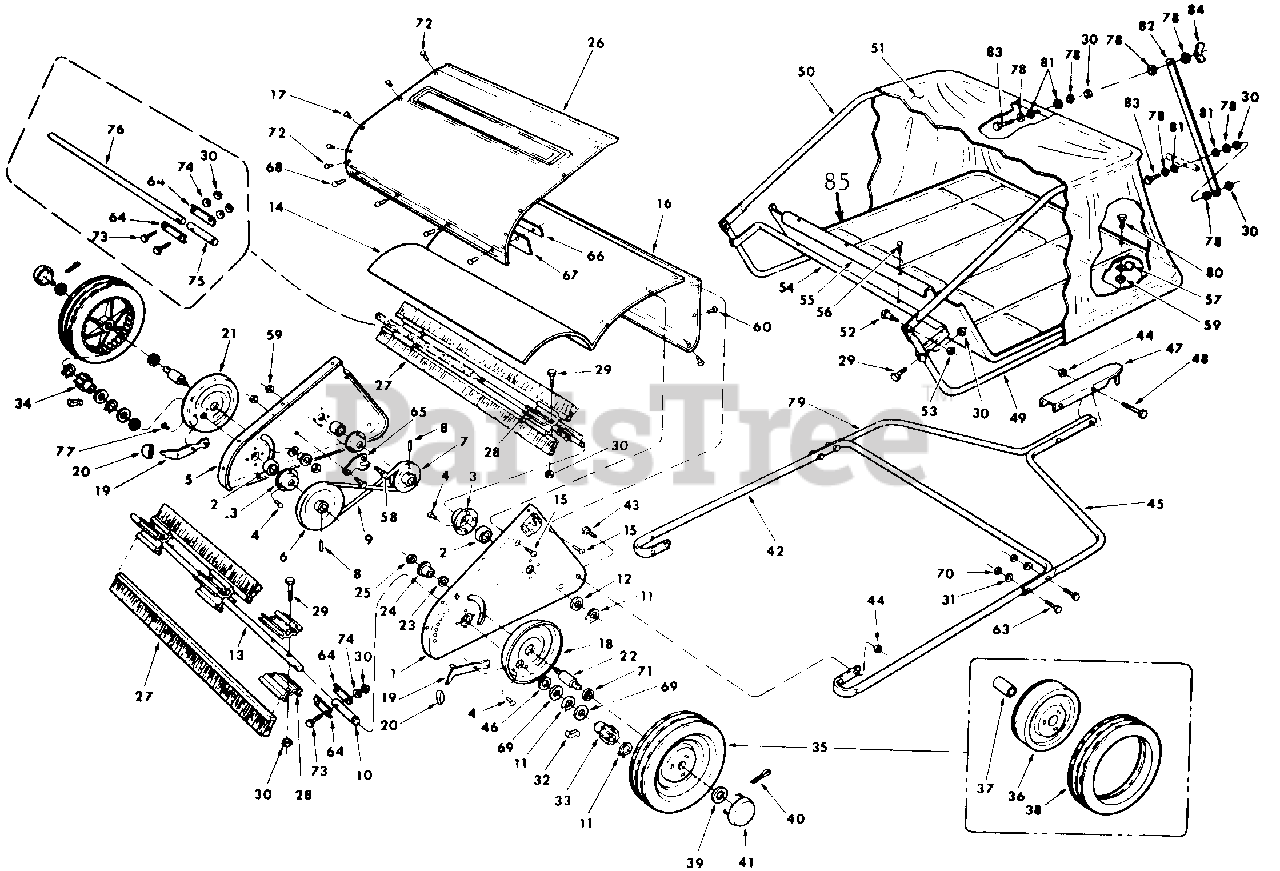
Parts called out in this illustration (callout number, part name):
1	Assembly-End Plate R.H.
2	Bearing
3	Retainer-Bearing
4	Rivet (3/16 Dia. x 5/16)
5	Assembly-End Plate L.H.
6	Assembly-Pulley
7	Pulley
8	Rollpin (.156 Dia. x 1-1/4)
9	Belt (3/8 Round Sect.)
10	Shaft-Brush Drive
11	Ring-Retainer
12	Washer-Flat (5/8 x 15/16 x 1/16)
13	Shaft-Brush Drive
14	Baffle-Top
15	Screw (10-32 x 1-1/8 Sems) *
16	Baffle-Front
17	Screw (10-32 x 3/8 Sems) *
18	Assembly-Dust Cover R.H.
19	Assembly-Wheel Adj. Lever
20	Knob-Wheel Adj.
21	Assembly-Dust Cover L.H.
22	Axle-Wheel
23	Washer-Bowed
24	Bushing-Spacer
25	Nut-Hex
26	Cover-Sweeper
27	Ass'y. Brush and Channel
28	Assemblv-Brush Retainer
29	Bolt (1/4-20 x 1-1/8 Hex Hd.) *
30	Nut (1/4-20 Hex Lock) *
31	Washer-Lock (5/16 Split)
32	Pawl
33	Pinion R.H.
34	Pinion L.H.
35	Assembly-Wheel
36	Wheel-Gear & Rim
37	Bushing
39	Washer (3/8 x 7/8 x 3/16) *
40	Cotter Pin (1/8 x 5/8) *
41	Cap-Hub
42	Draw-Bar-Rear
43	Bolt (5/16-18 x 3/4 Sem Hex) *
44	Nut (5/16-18 Hex Lock) *
45	Draw-Bar-Front
46	Washer-Bowed
47	Ass'y.-Bracket & Pin
48	Bolt (5/16-18 x 2-5/8 Hex Hd.) *
49	Frame Catcher-Lower
50	Frame Catcher-Upper
51	Basket-Fabric
52	Bolt-Shoulder
53	Nut (3/8-16 Hex Lock) *
54	Brace-Frame
55	Panel-Catcher Bottom
56	Screw (10-32 x 1/2 Phillips) *
57	Clamp
58	Bolt (10-32 x 3/8 Truss Hd.) *
59	Nut (10-32 Hex Lock) *
60	Screw (10-32 x 3/8 Sems) *
63	Bolt (5/16 x 1-3/8)
64	Coupling-Half
65	Scraper-Impeller Pulley
66	Retainer-Skirt
67	Skirt
68	Screw (10-32 x 3/8 Phillips Hd.) *
69	Washer (.59 x 1-1/8 x .015)
70	Nut (5/16-18 Hex)
71	Washer (.78 x 1-1/4 x .015)
72	Screw (10-12 x 5/8 Sheet Metal)
73	Bolt (1/4-20 x 1-1/4 Hex Hd.)
74	Lockwasher (1/4 Std. Split)
75	Shaft-Impeller
76	Shaft-Impeller
77	Rivet- (3/16 Dia. x 1/4 Truss Hd.)
78	Washer (17/64 x 3/4 x 1/16)
79	Draw & Bar-Front
80	Bolt (10-32 x 3/8 Hex Hd.)
81	Washer (21/64 x 3/4 x 3/32 Nylon)
82	Support
83	Bolt (1/4-20 x 13/4 Hex Hd.)
84	Nut 1/4-20 Wing-Lock
85	Vinyl Strip Edge 96" Lg.
